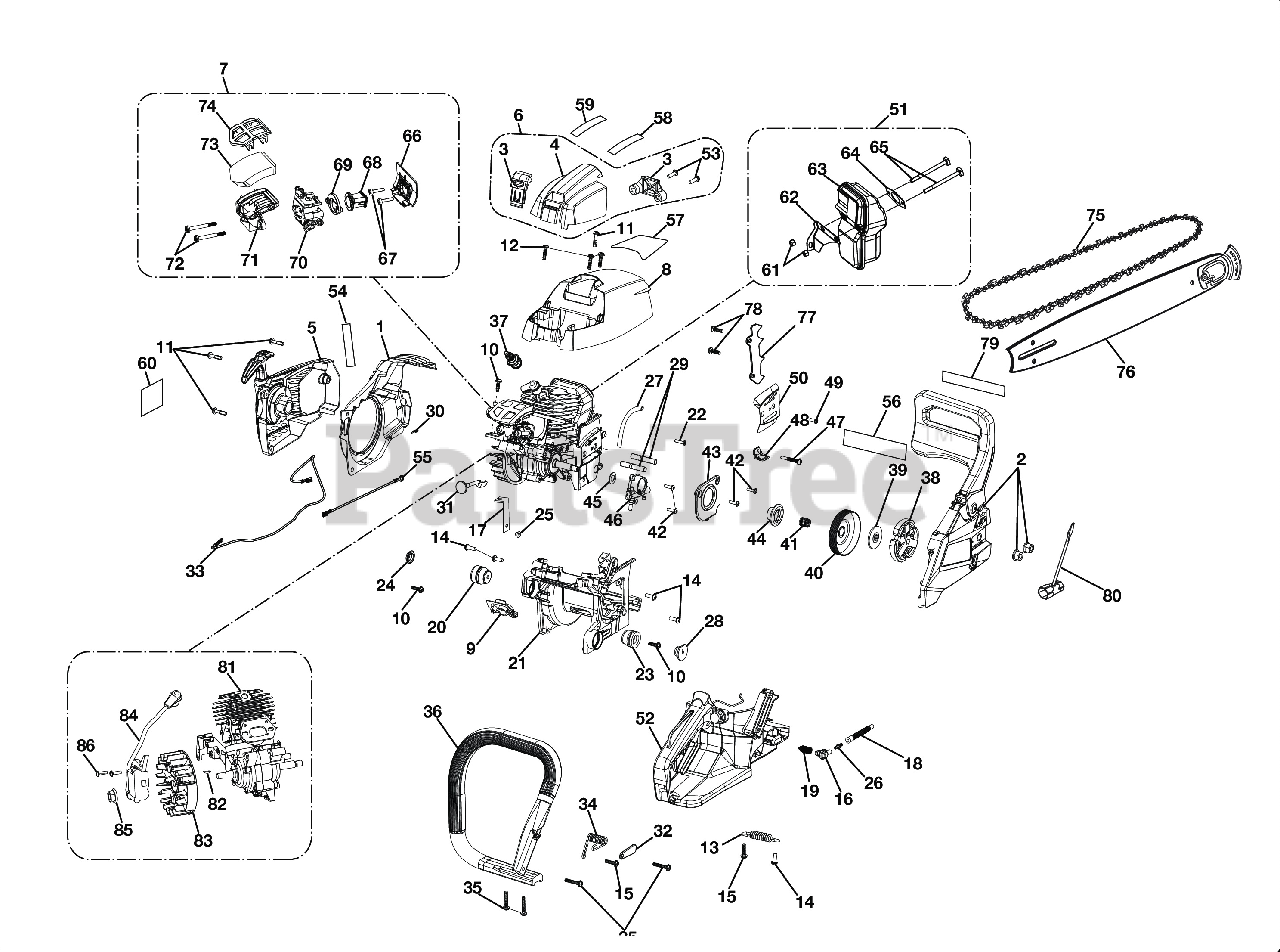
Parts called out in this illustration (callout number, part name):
1	Cylinder Baffle
2	Clutch Cover Assembly
3	Carburetor Cover Latch and Bracket Assembly
4	Carburetor Cover Housing
5	Starter Housing Assembly
6	Carburetor Cover Assembly
7	Intake Assembly
8	Cylinder Housing Assembly
9	Throttle Rod Grommet
10	Screw (M5 x 16 mm, T25 Torx Pan Hd.)
11	Screw, Truss Hd., Plastite (10-14 x 7/8")
12	Screw (M5 x 14 mm, T25 Torx Pan Hd.)
13	Damper Spring
14	Screw (M5 x 0.8 mm, T25 Torx Pan Hd.)
15	Screw (M5 x 14 mm, T25 Torx Pan Hd.)
16	Oil Filter Grommet
17	Band Stopper
18	Rubber, Pipe In Oil Pump
19	Cone Spring
20	Rubber Damper
21	Engine Case
22	Pin (Oil Pump Outlet)
23	Damper Rubber
24	Damper Cap.
25	Starter Case
26	Joint For Pipe In Comp
27	Oil Pump Rubber Tube (Outlet)
28	Damper Cap (T)
29	Bar Stud (5/16-18 x 23.5 mm / 5/16-18 x 18 mm)
30	Spring Clip (Choke Rod)
31	Choke Rod
32	Damper Plate
33	Lead Wire Assembly (Red)
34	Damper Spring
35	Screw (M5 x 27 mm, T25 Torx Pan Hd.)
36	Front Handle
37	Spark Plug (Bosch WSR6F)
38	Clutch Assembly
39	Thrust Plate
40	Clutch Drum
41	Clutch Drum Needle Bearing
42	Screw (M4 x 14 mm, T20 Torx Pan Hd.)
43	Oil Pump Cover
44	Oil Pump Drive Gear
45	Washer (Oil Pump Drive Gear)
47	Screw (M4 x 33 mm, T25 Torx Pan Hd.)
48	Chain Catcher.
49	Screw (M4 x 12 mm, T20 Torx Pan Hd.)
50	Chain Guard Plate.
51	Exhaust Assembly.
52	Chassis & Handle Components
53	Screw (M4 x 10 mm, T20 Torx Pan Hd.)
54	Warning Label (Combustion)
55	Lead Wire Assembly (Black)
56	Chain Brake Label (RY3818)
57	Warning Label
58	Starting Label (Right)
59	Starting Label (Left)
60	Starting House Label (RY3818)
61	Hex Nut (M5, Muffler)
62	Muffler Bracket
63	Muffler
64	Gasket (Muffler).
65	Screw (M5 x 0.8 mm, T25 Torx Pan Hd.)
67	Bolt (M9 x 19 mm, T25 Torx Pan Hd.)
68	Intake Boot
69	Intake Bracket
70	Carburetor Assembly
71	Air Box Base
72	Screw (M5 x 44 mm,T25 Torx Hd. Carburetor)
73	Foam Air Filter
74	Air Filter Retainer
75	18 in. Chain (3/8LP, 62DL)
76	18 in. Guide Bar Assembly
77	Bucking Spike
78	Screw (M5 x 11 mm., T25 Torx Pan Hd.)
79	Pull To Release Brake Label
80	Combination Wrench
81	Short Block
82	WOODRUFF KEY (10 mm X 3 mm)
83	Flywheel Assembly
84	Ignition Assembly
85	Flange Nut (M8, Flywheel)
86	Screw (M4 x 14 mm, T20 Torx Pan Hd.)
